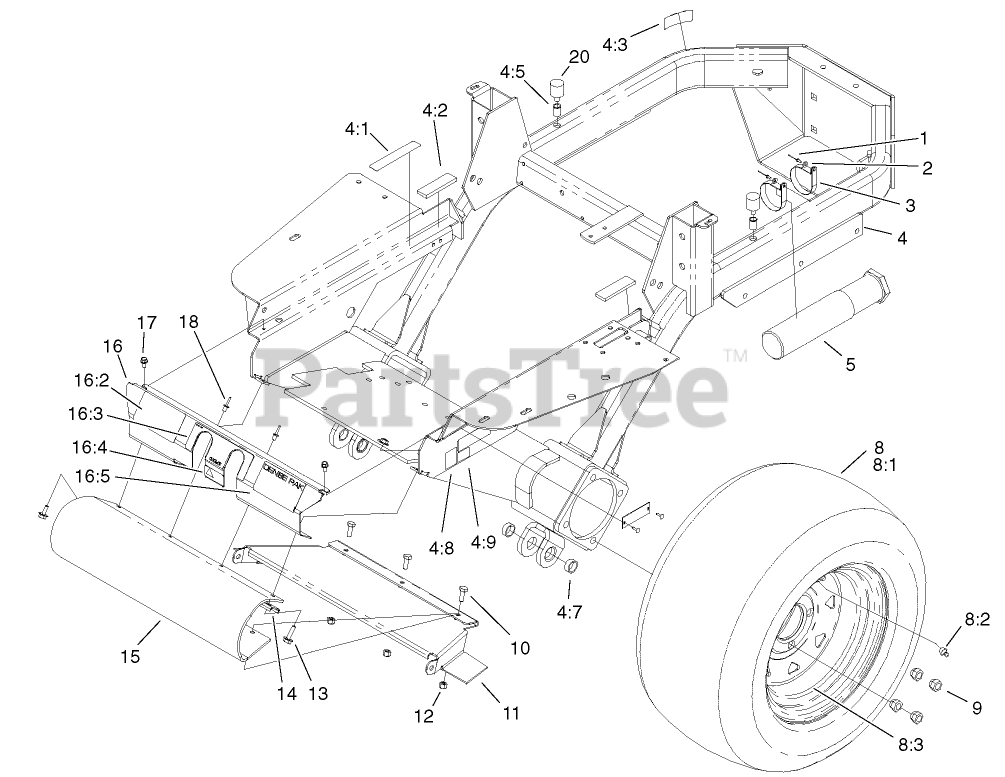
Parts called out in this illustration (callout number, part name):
1	RIVET-BLIND
2	WASHER-FLAT
3	CLAMP-R
4	FRAME ASM
4:1	DECAL-WARNING
4:2	PAD-RUBBER
4:3	DECAL-SURFACE, HOT
4:5	INSERT-THREADED
4:7	BUSHING
4:8	DECAL-LEVEL, NOISE
4:9	Decal-90 Lpa
5	TUBE-MANUAL
8	Tire And Wheel ASM
8:1	TIRE
8:2	STEM-VALVE
8:3	WHEEL
9	NUT-LUG
10	SCREW-HH
11	COVER-DRIVESHAFT
12	NUT-LOCK, NI
13	SCREW-HWH, THREAD ROLL
14	BRACKET-GUARD
15	GUARD-FOOTREST
16	COVER PLATE ASM
16:2	DECAL - Z350
16:3	DECAL-CONTROL, STEERING
16:4	DECAL-PROTECTION, EAR
16:5	DECAL-PAK, DENSE
17	SCREW-HWH
18	RIVET-BLIND
20	BUMPER-RUBBER
